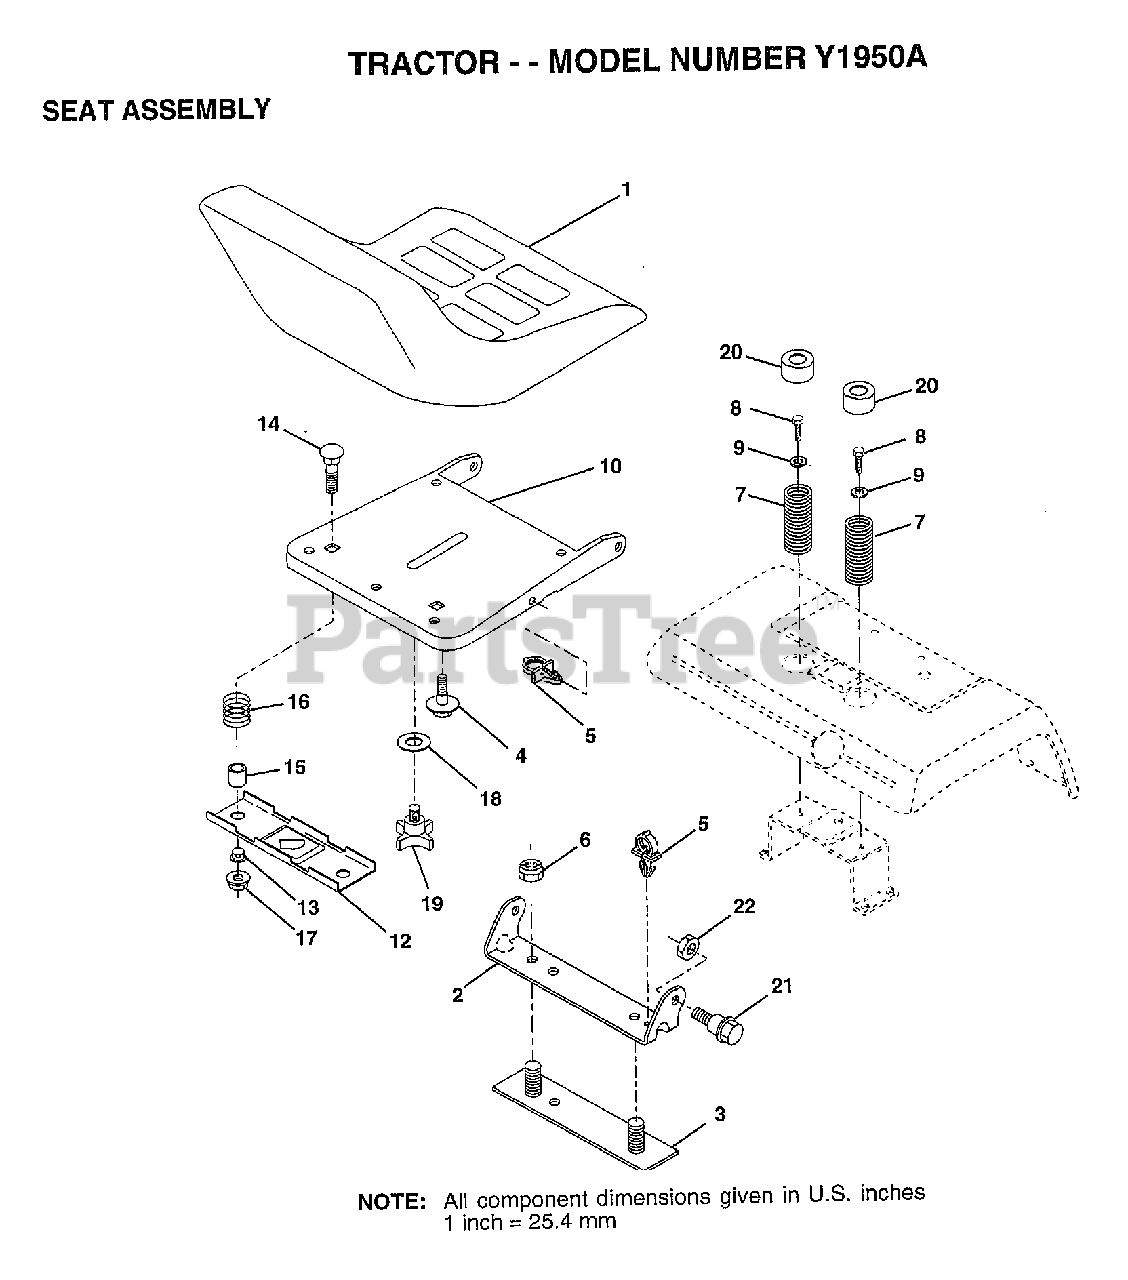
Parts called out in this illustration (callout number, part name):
2	BRACKET PVT SEAT
3	STRAP ASM FENDER
4	"BOLT,SHOULDER"
5	CLIP.PUSH-IN.HING
7	SPRING COMPRESSIO
8	SCREW LT
9	WASHER
12	BRKT SWITCH
13	BUSHING
15	SPACER SPLIT
16	SPRING COMPRESSED
18	WASHER
19	"KNOB 1/2"" YT"
20	CAP SPRING
21	BOLT.SHLD.5/16-18
